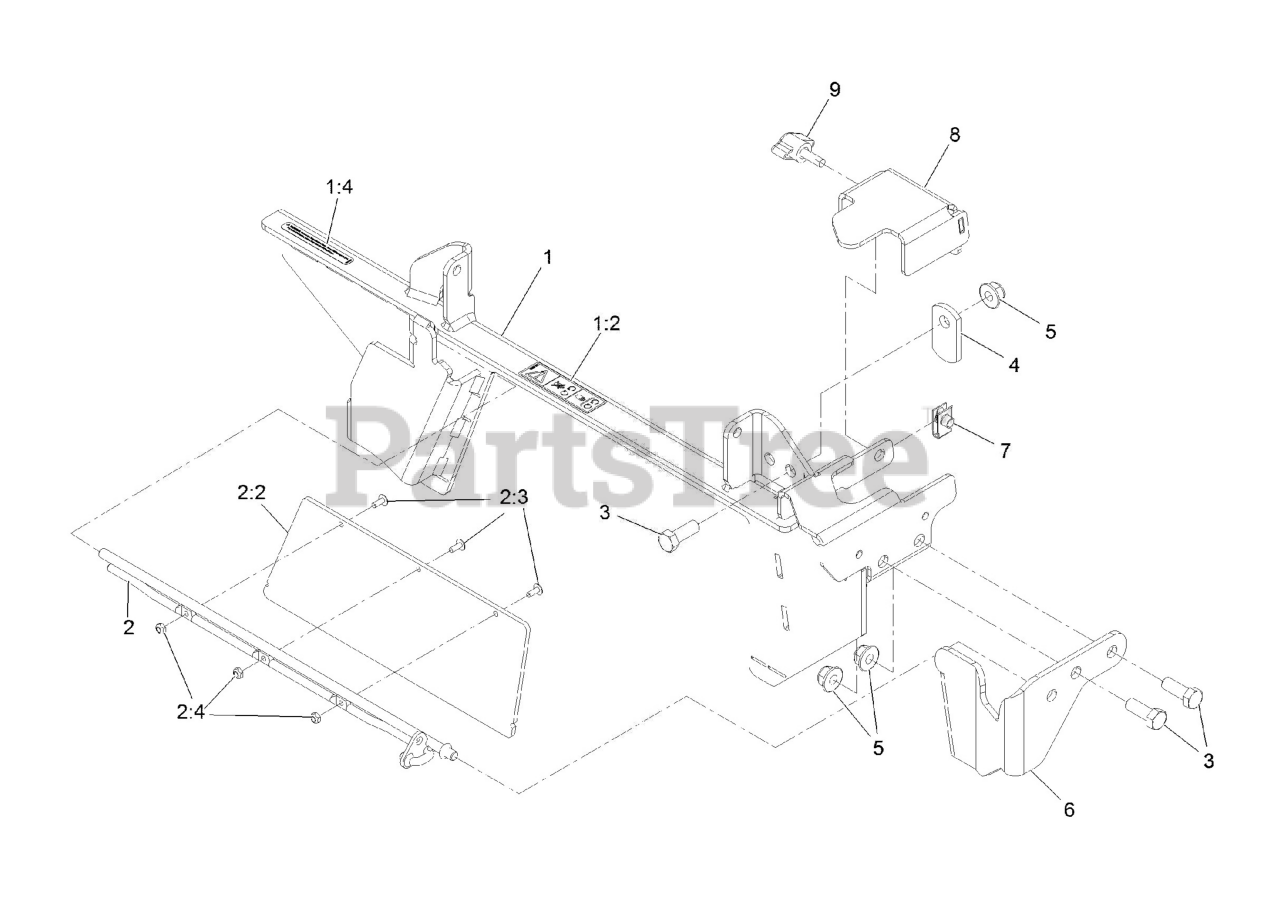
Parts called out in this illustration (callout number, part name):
1	OCD FRAME ASM W/ DECALS
1:2	DECAL, COVER MISSING
1:4	DECAL-WARNING
2	OCD GATE ASM
2:2	GATE-OCD
2:3	SCREW-PTH
2:4	NUT-LOCK, NI
3	SCREW-HH
4	LATCH-CATCHER, GRASS
5	NUT-HF, NI
6	BRKT,CHUTE FRONT
8	BRACKET, CABLE MOUNT
